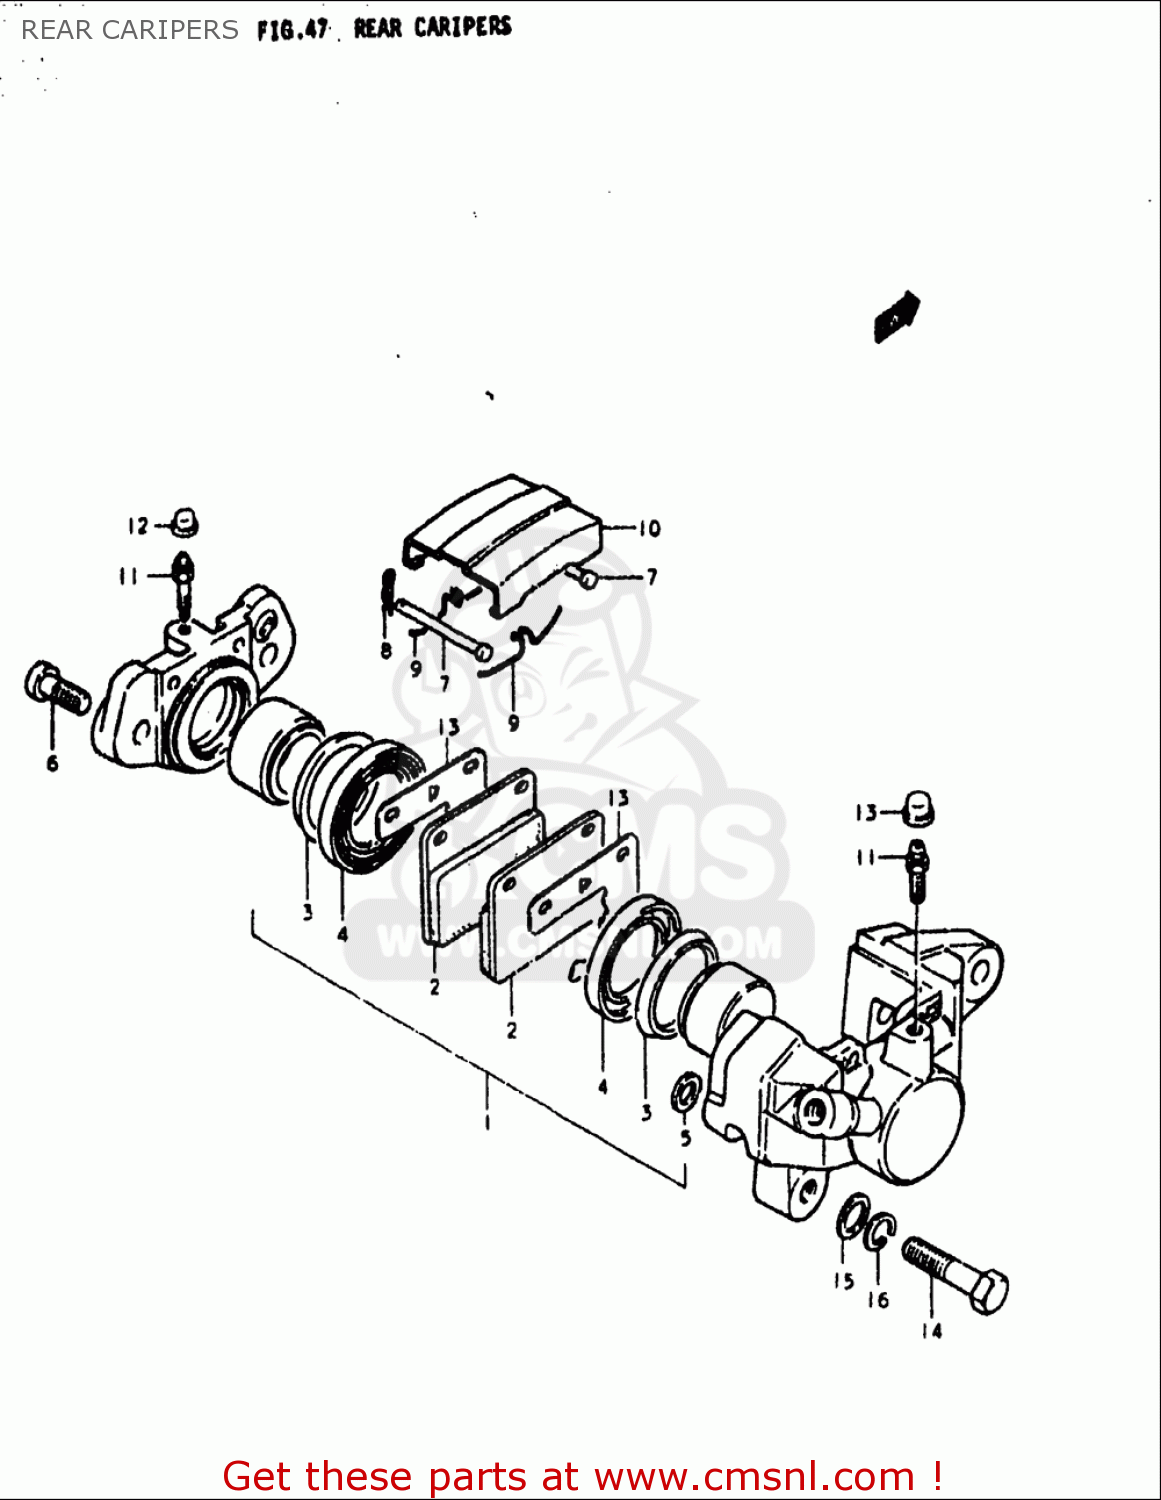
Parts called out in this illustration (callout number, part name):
1	PISTON SET
2	PAD SET (NAS)
3	SEAL,PISTON
4	BOOT,PISTON
5	SEAL,PISTON
6	BOLT,HOUSING
7	PIN,PAD
8	CLIP,PAD PIN
9	SPRING
10	COVER,DUST
11	BLEEDER
12	CAP,BLEEDER PLUG
13	SHIM,RR CALIPER
14	BOLT(10X34)
15	WASHER
16	WASHER,LOCK
